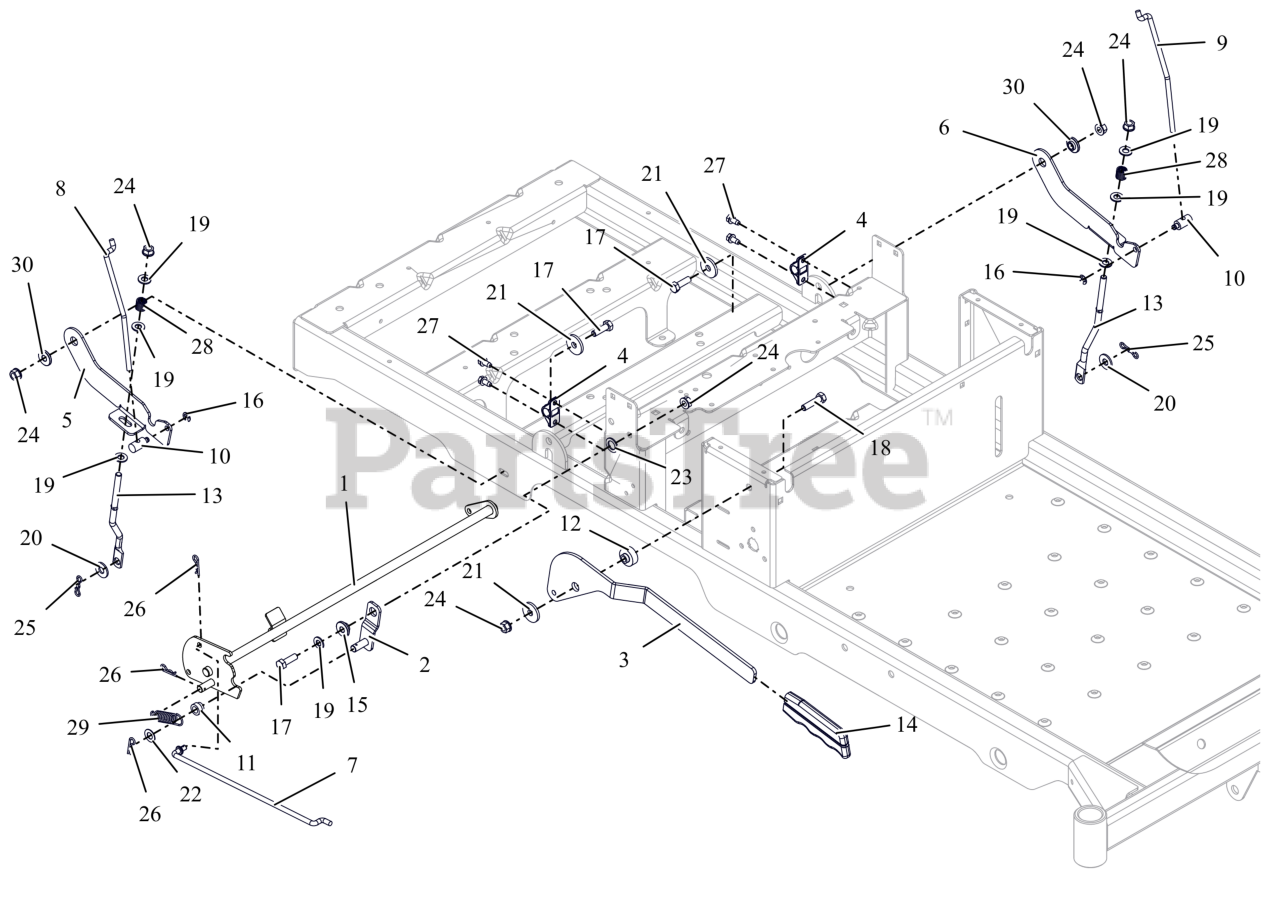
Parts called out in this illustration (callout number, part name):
1	WLDMT, BRAKE SHAFT (BLACK)
2	WELDMENT,DETENT ARM
3	HANDLE, PARKING BRAKE
4	BUSHING-.50 CLAMP BLOCK MOLDED
5	LATCH,RH NETURAL
6	LATCH,LH NETURAL
7	LINK, BRAKE HANDLE
8	LINK, NEUTRAL RH
9	LINK, NEUTRAL LH
10	TRUNION, 1/4-20
12	SPCR,BRAKE .32X.49X.192X1.00
13	LINK, BRAKE COG
14	GRIP, PARKING (GRAY)
15	BSHG-FLG .32X.500X.344X.880
16	RG-RTNG-EXT .250X.025
17	BLT,HEX .31-18X1.00 G5 ZCC
18	BLT, HEX .31-18X1.25 G5 ZCC
19	WSHR,FLT .344X.688X.065 ZCC
20	WSHR,FLT .375X.875X.083 ZCC
21	WSHR, FLT .340X1.125X.135 ZCC
22	WSHR, FLT .385X.745X.030 ZCC
23	WSHR, FLT .520X.827X.062 ZCC
24	NUT,LK-CTR-FLG .31-18 GF ZCC
25	PIN, BOWTIE #72 ZCC
26	PIN, HAIR #213 .08X1.19 ZCC
27	SCR-TAP .25-20X.50 HWH ZCC
28	SPRING, COMPRESSION
29	SG-TENS .072X.565X1.87
30	BSHG, FLG .325X.499X.26X.88
